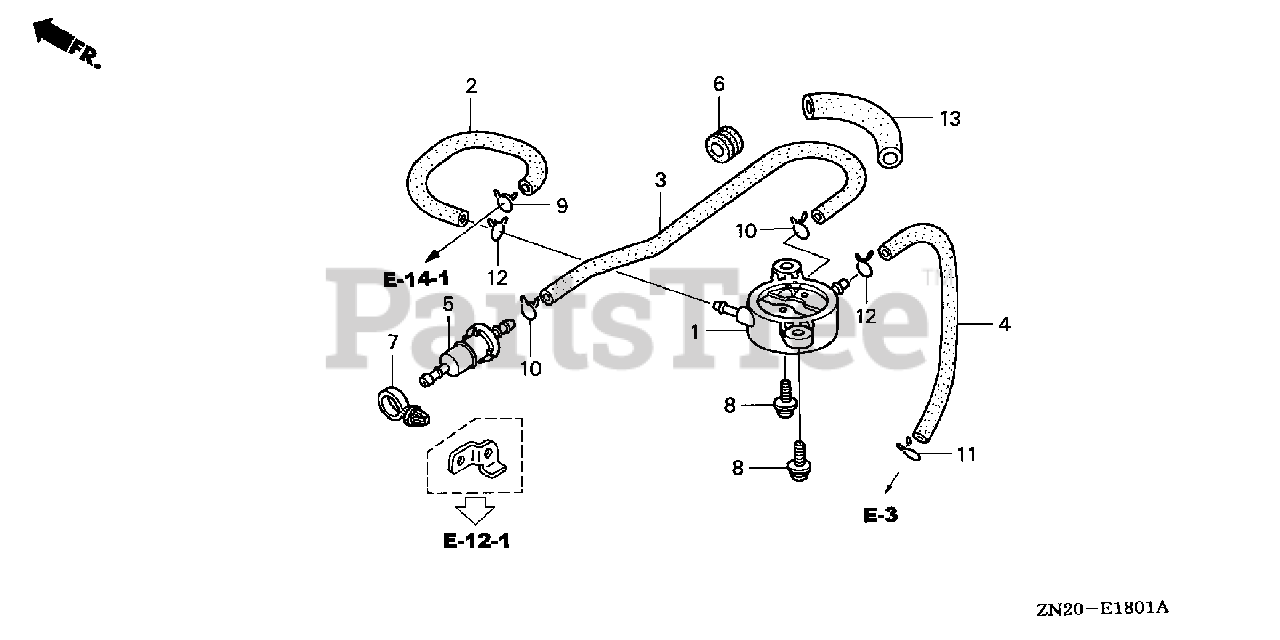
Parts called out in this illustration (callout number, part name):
1	PUMP ASSY., FUEL
2	TUBE, FUEL
3	TUBE B, FUEL
4	TUBE, DIAPHRAGM
5	FILTER, FUEL
6	GROMMET, RESERVE TANK
7	CLIP, WIRE HARNESS
8	SCREW-WASHER (6X16)
9	CLIP, TUBE (B8)
10	CLIP, TUBE (B10)
11	CLIP, TUBE (C9)
12	CLIP, TUBE (C11)
13	BULK HOSE, VINYL (11X13X3000) (11X13X50)
